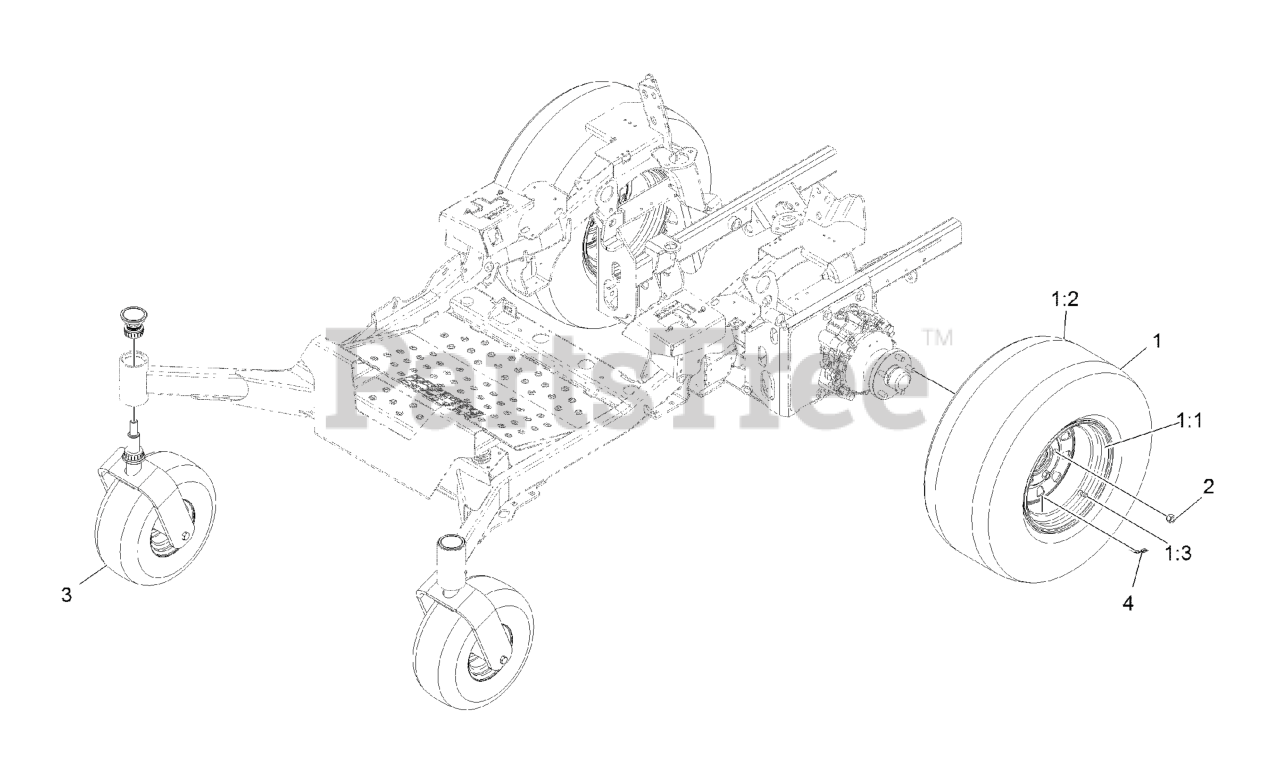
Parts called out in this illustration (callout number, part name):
1	ASM-TIRE 26 X 12-12
1:1	RIM ASM
1:3	Stem-Valve
2	NUT-LUG
3	ASM, Wheel Caster
4	DECAL-TORQUE, WHEEL NUT
